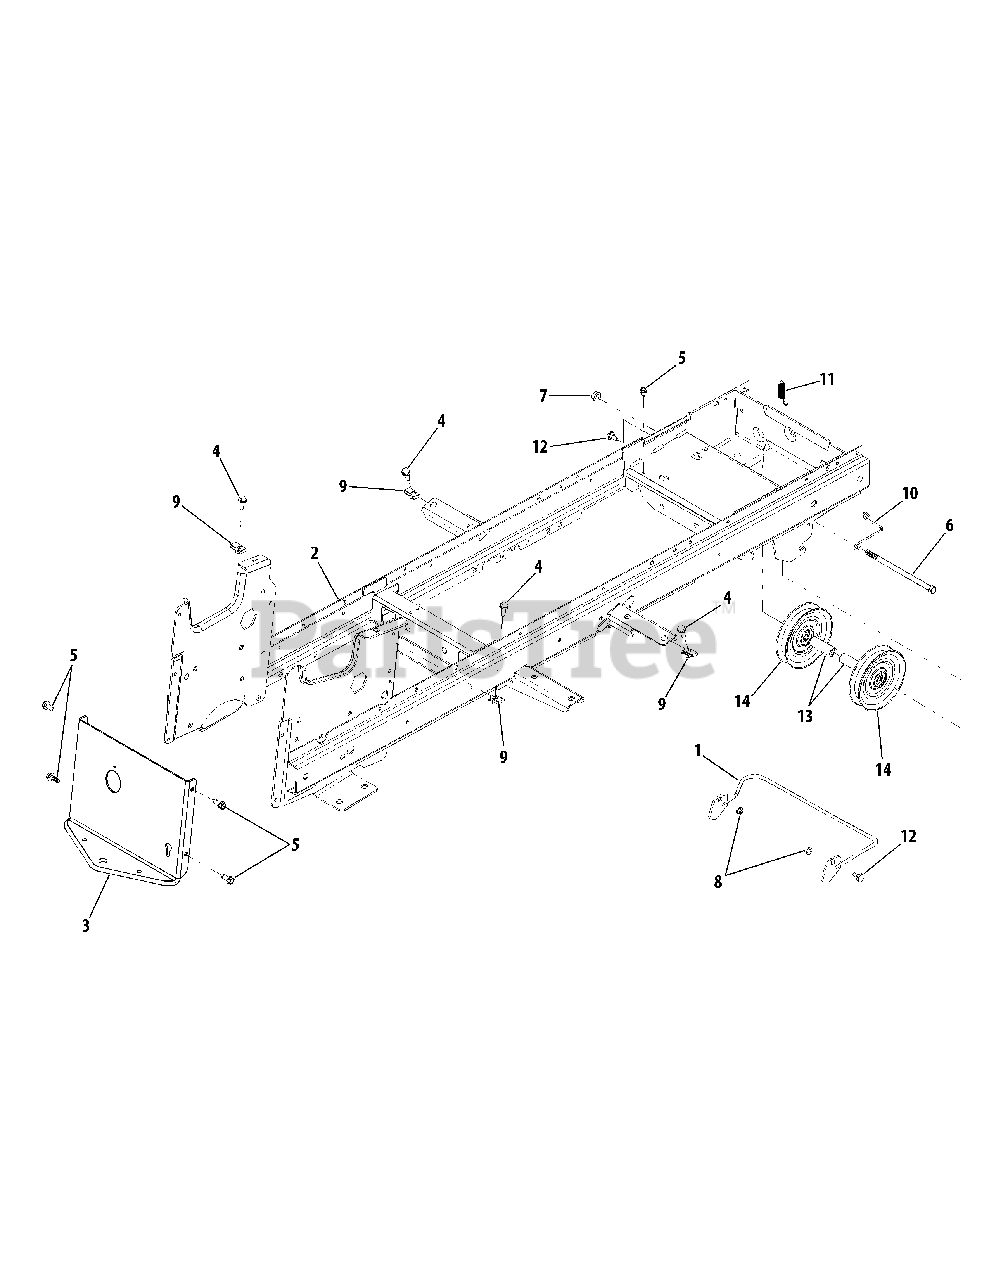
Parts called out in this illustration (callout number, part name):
1	Rod, Quick Attach
4	Screw, Hex Wsh Hd Tapp 5/16-18 x 1.0
5	Screw, Hex Wsh Hd Tap 5/16-18 x .75
6	Screw, Hex Cap, 3/8-16 x 7.0
7	Nut, Hex Flange Lock, 3/8-16
8	Nut, Hex Flange Lock, 1/4-20
9	U-Nut, 5/16-18
10	Belt Guide
11	Spring, Latch
12	Bolt, Shoulder
13	Spacer, Idler, .411 x .720 x 2.19
14	Pulley, Idler
